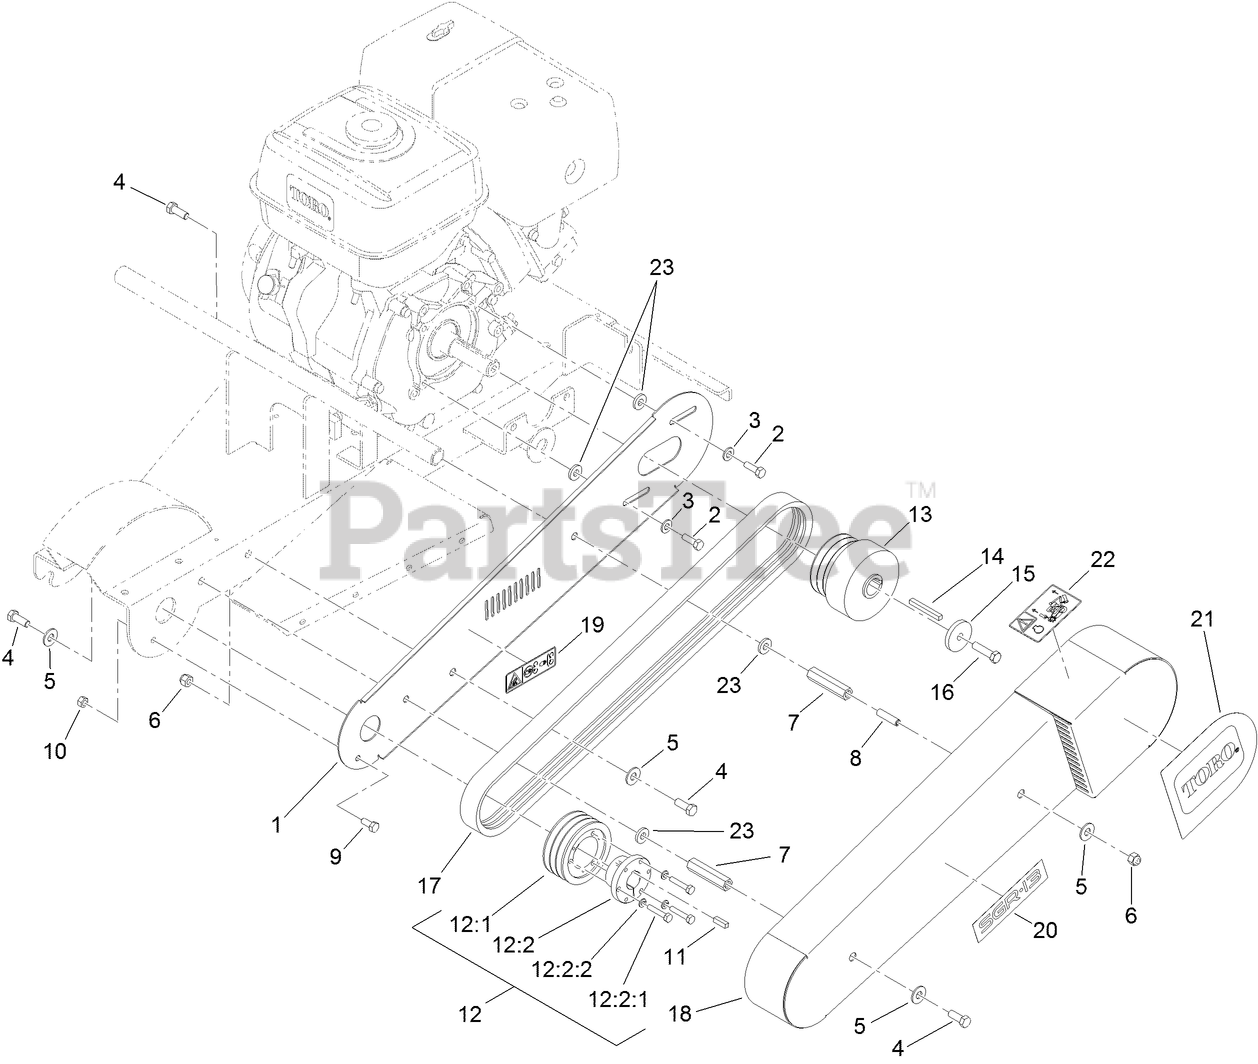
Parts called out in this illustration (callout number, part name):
1	PLATE-BELT GUARD, INNER
2	SCREW-HH
3	WASHER-FLAT
4	SCREW-HH
5	WASHER-FLAT
6	NUT-LOCK, NI
7	SPACER-GUARD
8	SCREW-SET, HSH
9	SCREW-HH
10	NUT-HEX
11	KEY-SQUARE
12	SHEAVE ASM
12:1	PULLEY
12:2	BUSHING
12:2:1	SCREW-HH
12:2:2	WASHER-LOCK
13	CLUTCH
14	KEY-SQUARE
15	WASHER-PLAIN
16	SCREW-HH
17	BELT-3V
18	BELT GUARD ASM
19	DECAL-WARNING, SHIELDS
22	DECAL-CAUTION
23	SPACER
